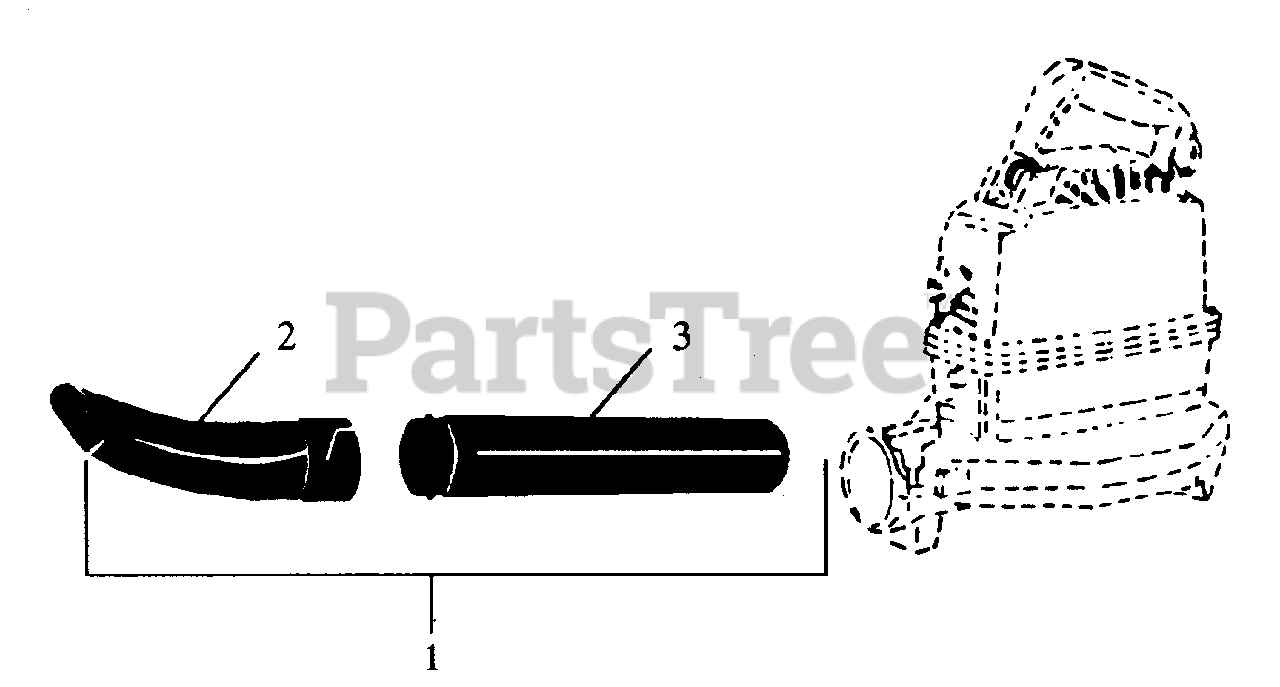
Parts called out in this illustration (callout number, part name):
1	Blower Tube Kit
2	Blower Nozzle
3	Blower Tube
